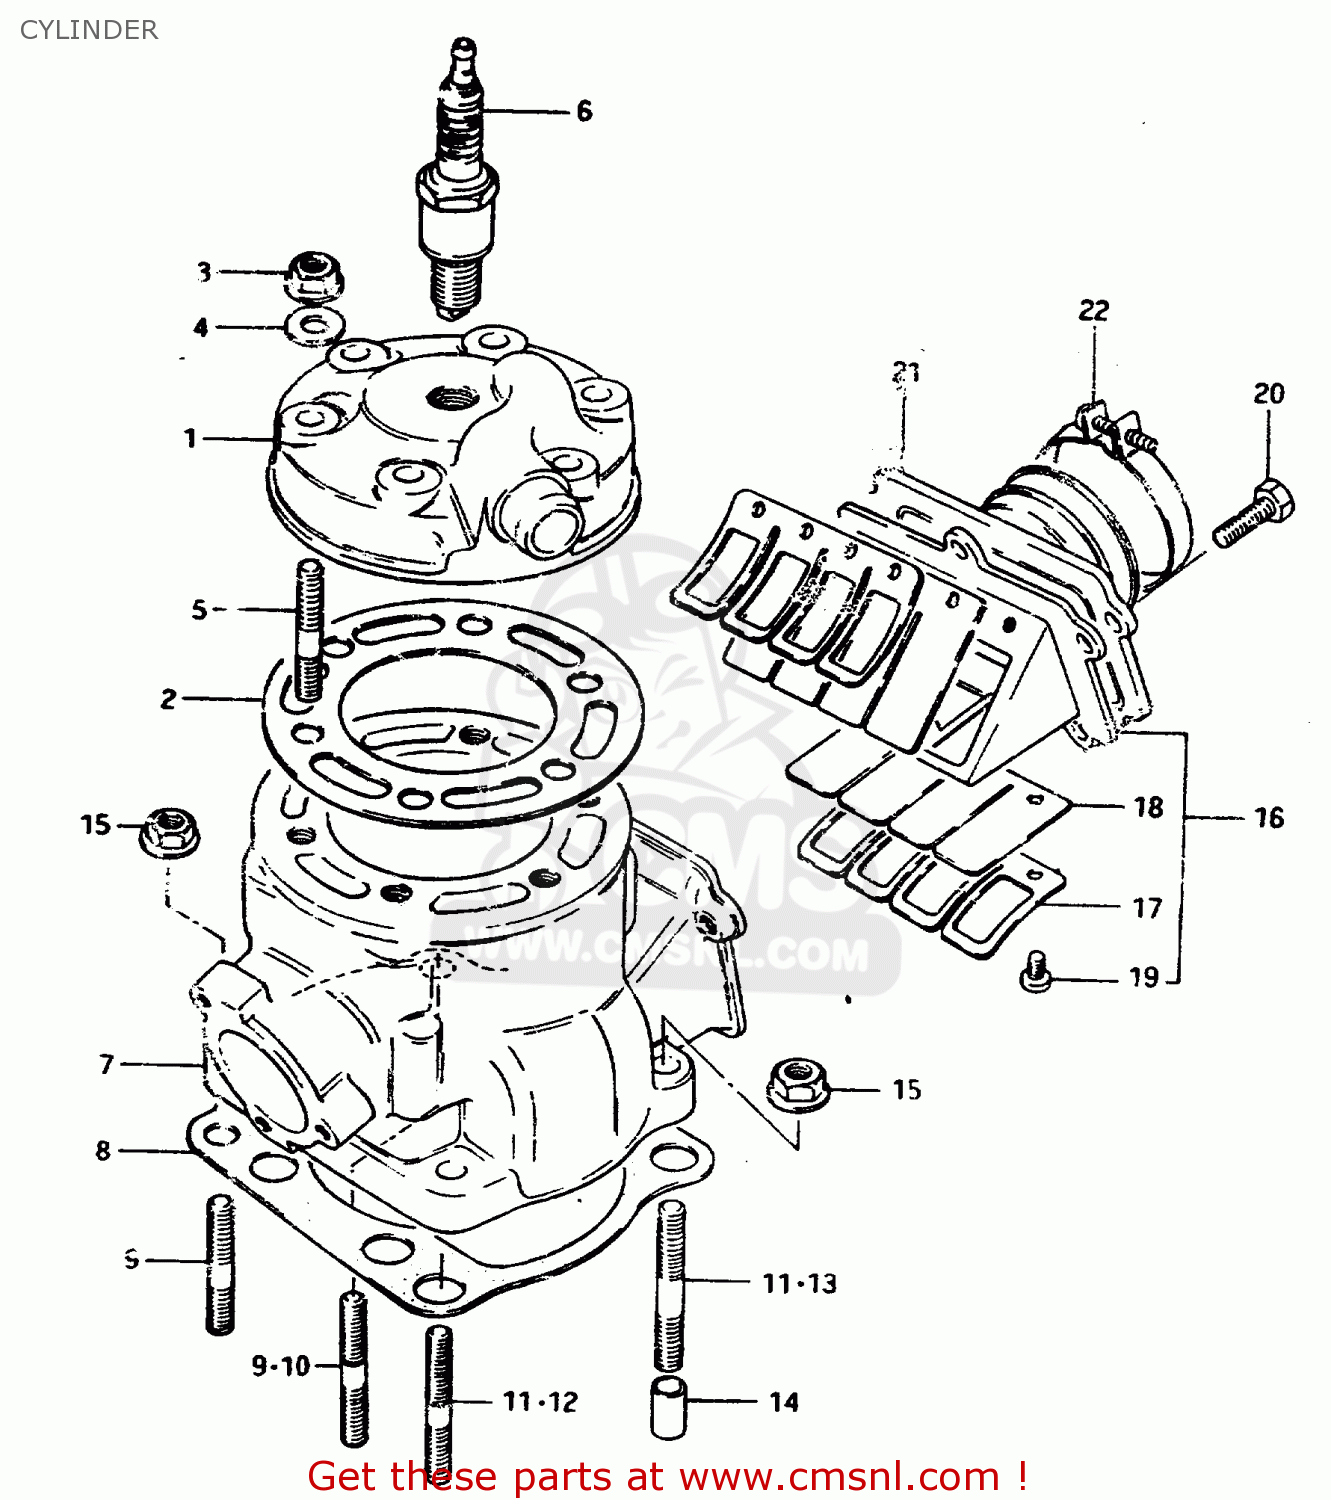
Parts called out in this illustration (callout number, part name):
1	HEAD,CYLINDER
2	GASKET,CYLINDER HEAD (NAS)
3	NUT 8MM
4	WASHER (8.5X19X2.3)
5	STUD
6	PLUG,SPARK(NGK B-8EN)
7	CYLINDER
8	GASKET,CYLINDER (NAS)
9	BOLT,STUD
10	BOLT,STUD
11	BOLT,STUD
12	BOLT,STUD
13	BOLT,STUD
14	STUD
15	PIN
16	NUT 8MM
17	VALVE ASSEMBLY,REED
18	STOPPER,REED VALVE
19	VALVE,REED
20	SCREW
21	BOLT
22	PIPE,INTAKE
23	CLAMP
